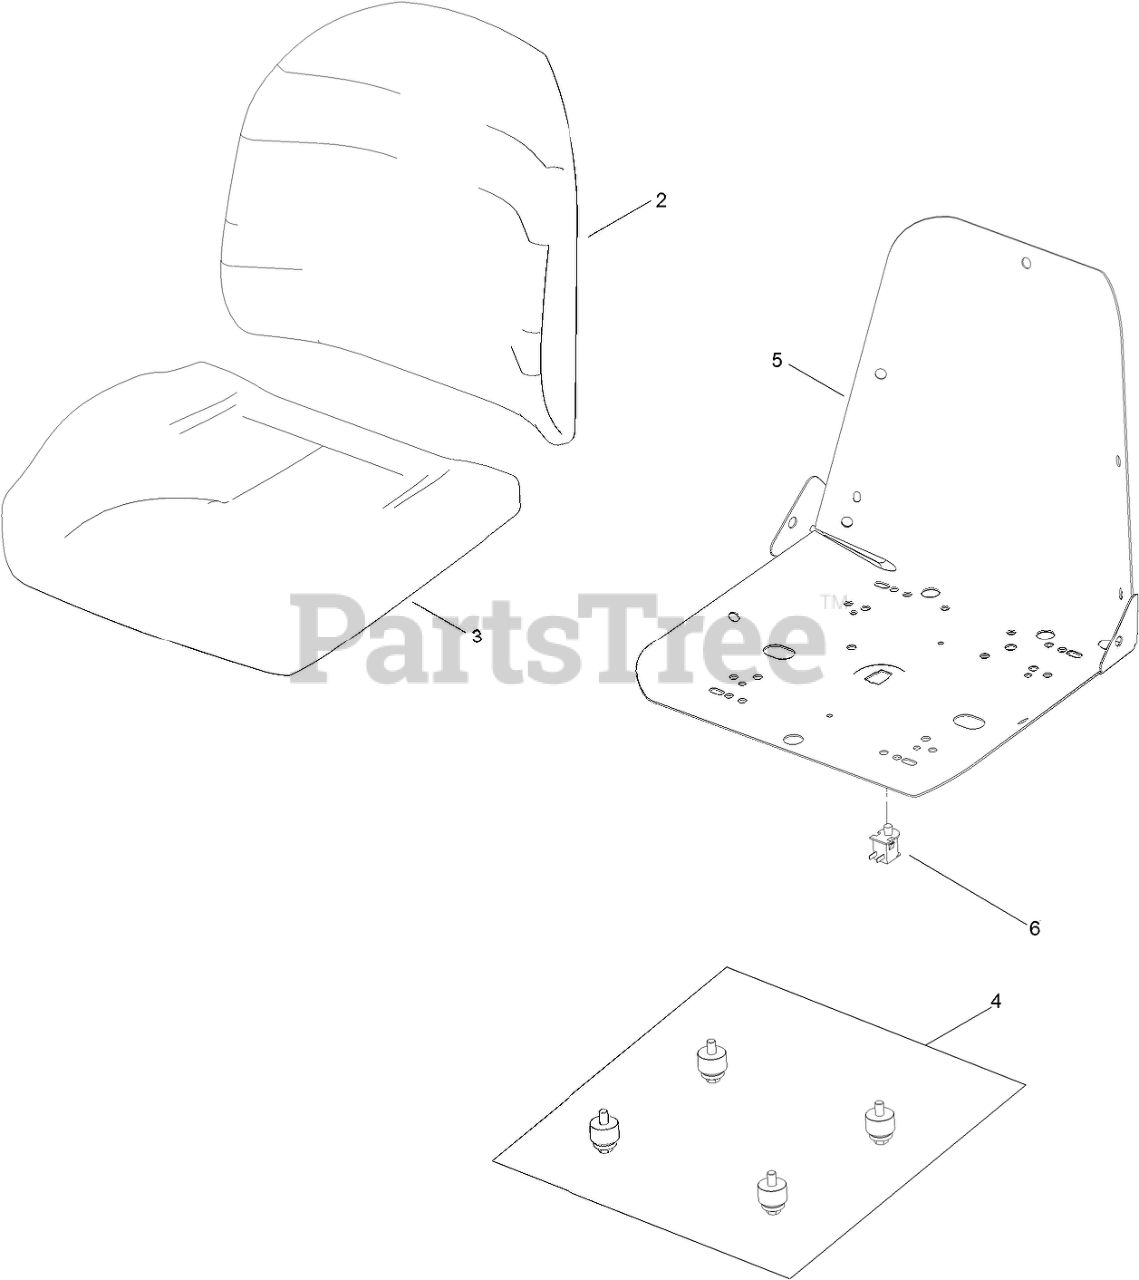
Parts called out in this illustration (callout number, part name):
2	CUSHION-SEAT, BACK
3	CUSHION-SEAT, BOTTOM
4	BUSHING ASM
6	SWITCH-BAIL
